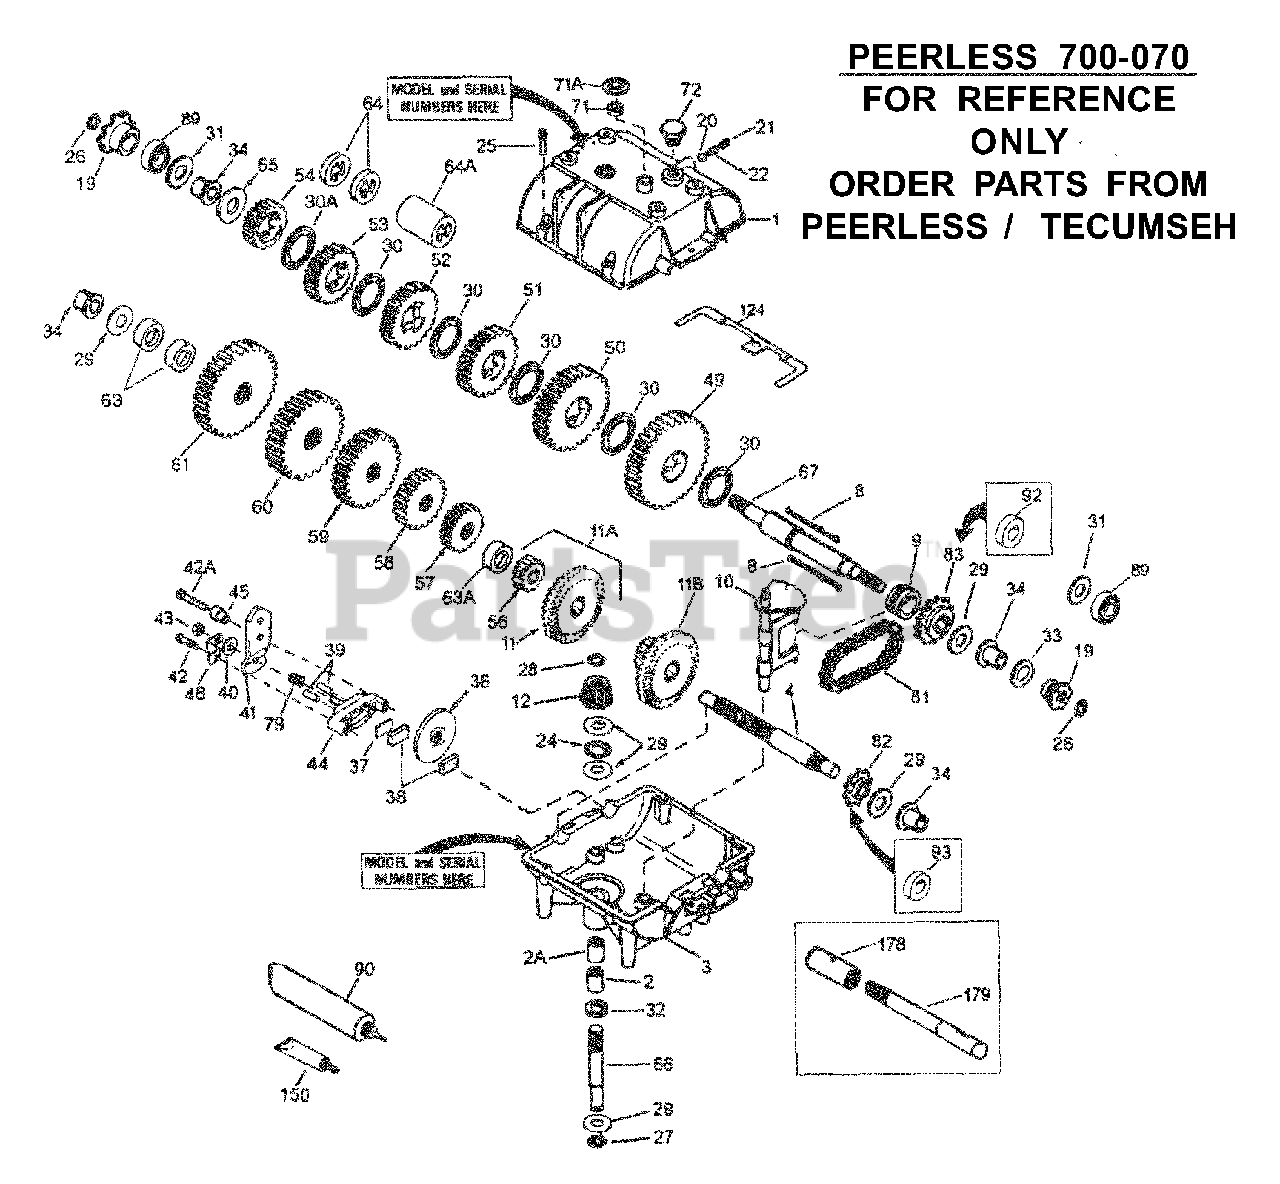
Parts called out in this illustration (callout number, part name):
1	Case, Transmisson
2	Needle Bearing Grease Spec
2A	Needle Bearing
3	Case, Transmission
8	Shift Key
9	Shift Collar
10	Shift Rod & Fork
11	Bevel Gear (42 teeth)
12	Bevel Pinion (14 teeth-steel)
20	Steel Ball, 5/16" dia.
21	Set Screw, 3/8-16 x 3/8"
22	Spring
24	Thrust Bearing
25	Screw, 1/4-20 x 1-1/4" (6)
27	Retaining Ring
28	Retaining Ring
29	Washer (6)
30	Washer (5)
32	"O" Ring
34	Flanged Bushing
49	Spur Gear (37 teeth)
50	Spur Rear (35 teeth)
51	Spur Gear (32 teeth-steel)
52	Spur Gear (30 teeth)
53	Spur Gear (25 teeth)
56	Spur Gear (12 teeth-steel)
57	Spur Gear (15 teeth)
58	Spur Gear (18 teeth-steel)
59	Spur Gear (20 teeth)
60	Spur Gear (25 teeth)
65	Washer
66	Input Shaft (3-11/16" long)
67	Shifter & Brake Shaft
71	Square Cut Ring
72	Threaded Plug (Shipping only, not used)
81	Roller Chain (No. 41 chain, 24 links)
82	Sprocket (9 teeth)
83	Sprocket (18 teeth)
90	Grease (32 oz. bottle Bentonite grease)
150	Gasket Eliminator (Loctite #515)
178	Coupling
179	Connector Shaft
